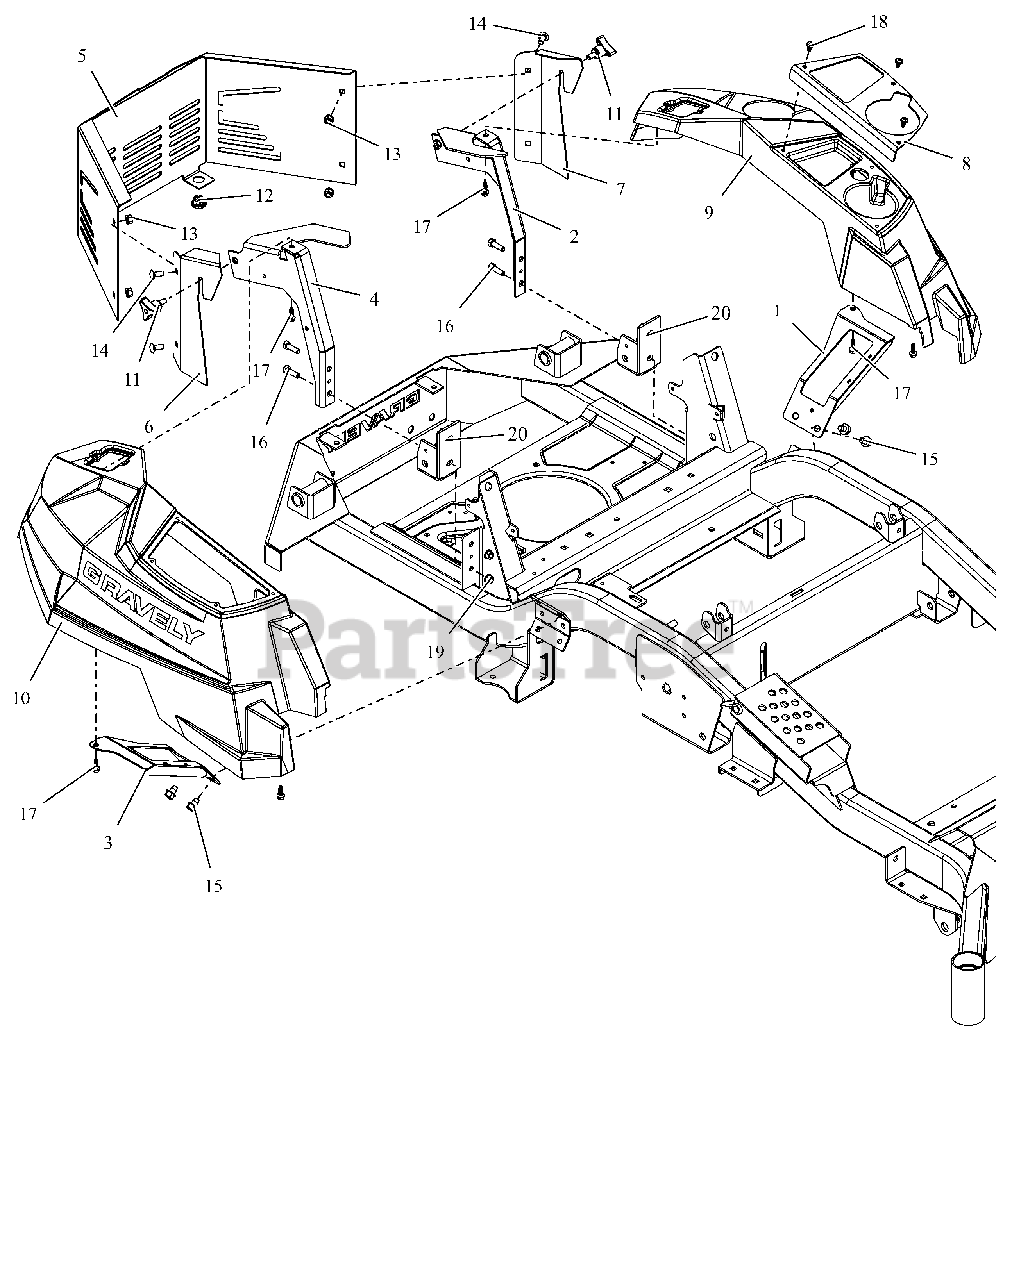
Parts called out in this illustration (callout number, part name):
1	WLDMT, LH FENDER MOUNT
2	BRKT, LH FENDER MTG
3	WLDMT, RH FENDER MOUNT
4	BRKT, RH FENDER MTG
5	GUARD, HD ENGINE
6	TRIM, HOOD STYLE (RIGHT)
7	TRIM, HOOD STYLE (LEFT)
8	PANEL, HD
9	KIT, FENDER W/FUEL DECAL-HD
10	FENDER, RH HD (2017) SHRT BOSS
11	KNOB,WING STUD 5/16-18 X .75
12	GROMMET, 10MM BOLLHOFF
13	NUT-LK-TOP-FLG .312-18 GF ZCC
14	BLT, RHSSN.31-18X.750 G5 ZCC
15	SCR,TAP .375-16X.50 HWH TR ZCC
16	BLT, HEX .31-18X1.00 G8 ZCC
17	SCR, PLASTITE-HWH 0.25 X 0.75 ZC120
18	SCR-PAN .25-15X.50 6L H/LZB500
19	NUT,LK-CTR-FLG .31-18 GF ZCC
20	BRKT, ROPS SUPPORT
